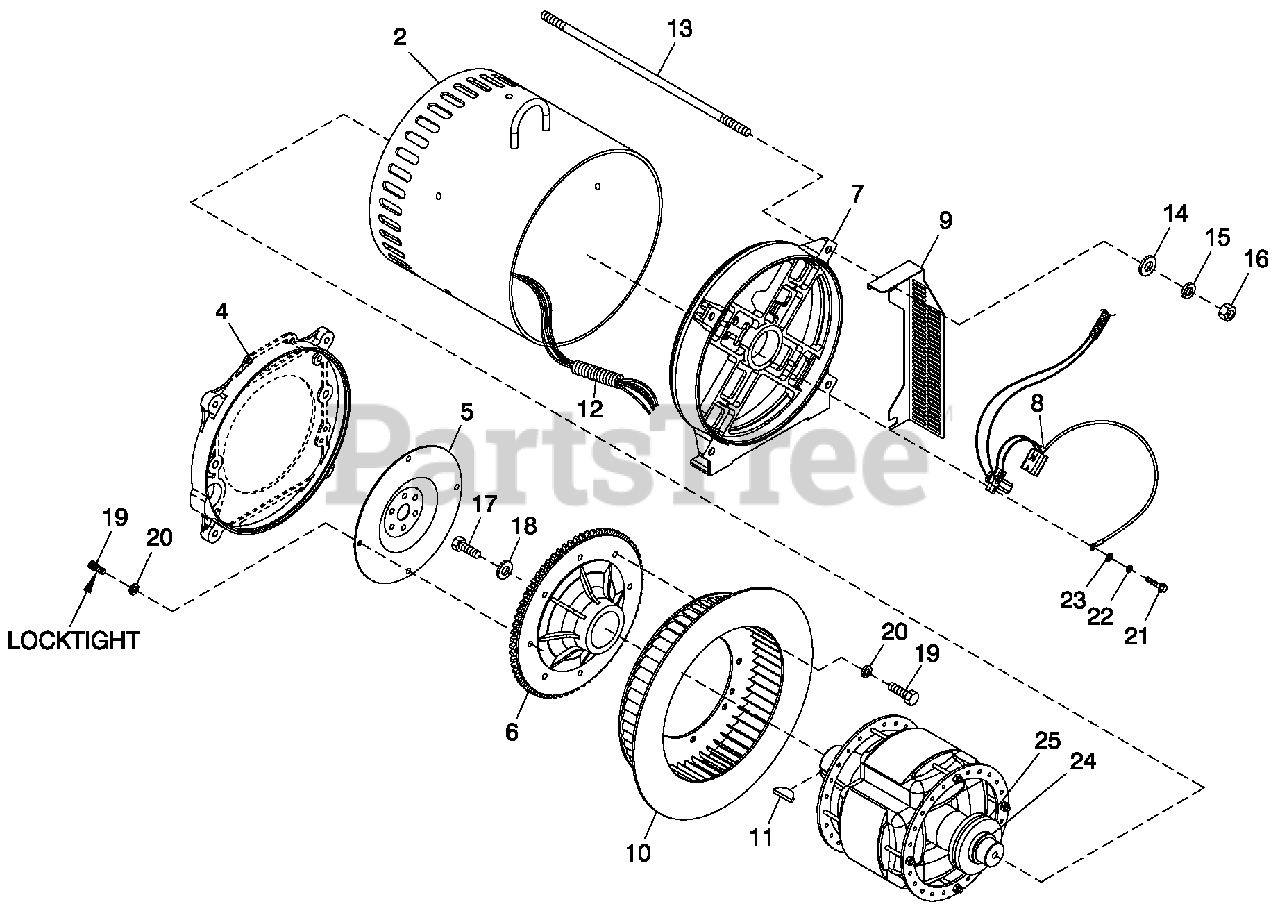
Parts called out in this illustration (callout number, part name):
1	RTR 390 30AD1 CPL
2	STR 390 30AD1 CPL
3	INSTR HYPOT TEST
4	ENGINE ADAPTER
5	FLEXPLATE
6	ASSY FLYWHEEL C2 CPL
7	REAR BEARING CARRIER 390/DRCT
8	ASSY BRUSH HOLDER 390/HSB
9	GUARD REAR BEARING CARRIER CPL 3.0L 30KW
10	REVCOR FAN 12.63 X 2 W/PRESSDISK
11	KEY WOODRUFF #E
12	CONDUIT FLEX 1-1/4" (30” LG)
13	STUD M14-2.0 570 G5 ZINC (30KW)
14	WASHER FLAT M14
15	WASHER LOCK M14
16	NUT HEX M14-2.0 G8 YEL CHR
17	SCREW HHC M16-2.0 X 45 G8.8
18	WASHER FLAT .688 ID X 3.25 OD
19	SCREW SHC M10-1.5 X 16 G10.9
20	WASHER LOCK M10
21	SCREW HHTT M4-0.7 X 25 BP
22	WASHER LOCK #8-M4
23	WASHER FLAT #8 ZINC
24	BALL BEARING-45 MM
25	SLIP RING MACHINED
